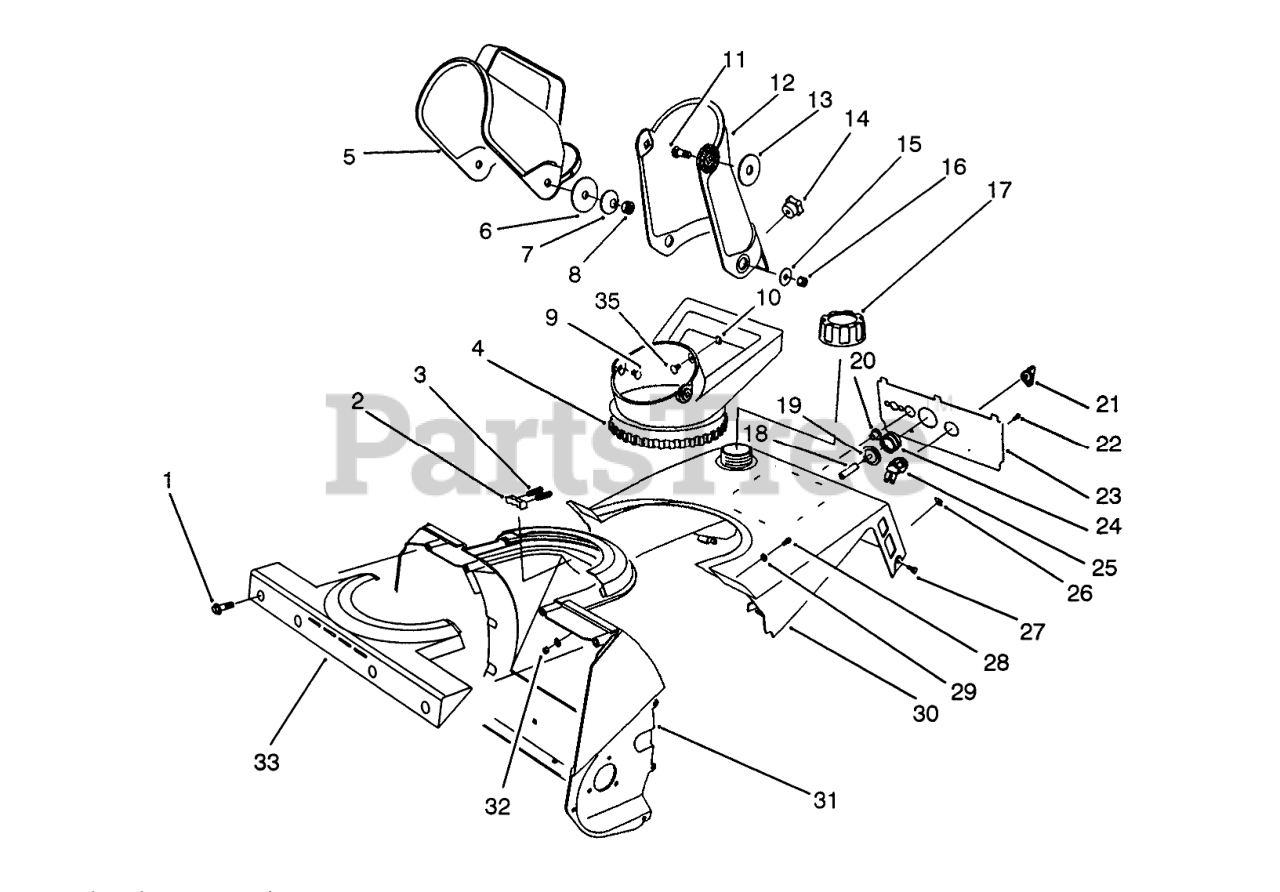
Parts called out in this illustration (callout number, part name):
1	SCREW-PLASTIC
2	DETENT-CHUTE
3	SPRING-COMPRESSION
4	HANDLE-CHUTE
5	DEFLECTOR-CHUTE
6	WASHER-FLAT
7	WASHER-BELLEVILLE
8	NUT-LOCK, NI
9	SCREW-HH
10	PUSHNUT-RETAINER, BOLT
11	BOLT-CARR
12	CHUTE
13	Washer-Rubber
14	KNOB-CHUTE
15	WASHER-FLAT
16	NUT-LOCK, NI
17	CAP-FUEL ASM
18	HOSE-PRIMER
19	BODY-PRIMER
20	GUIDE-ROPE, STARTER
21	KEY-IGNITION
22	SCREW-SHWH, THREAD FORMING
23	CNTRL PNL/SILK SCRN
24	BULB-PRIMER
25	SWITCH
27	SCREW-THREAD FORMING
28	SCREW-PPH
29	WASHER-FLAT
30	Shroud-Upper
31	HOUSING
32	NUT-LOCK, NI
33	RETAINER-CHUTE
35	SCREW-CARR
